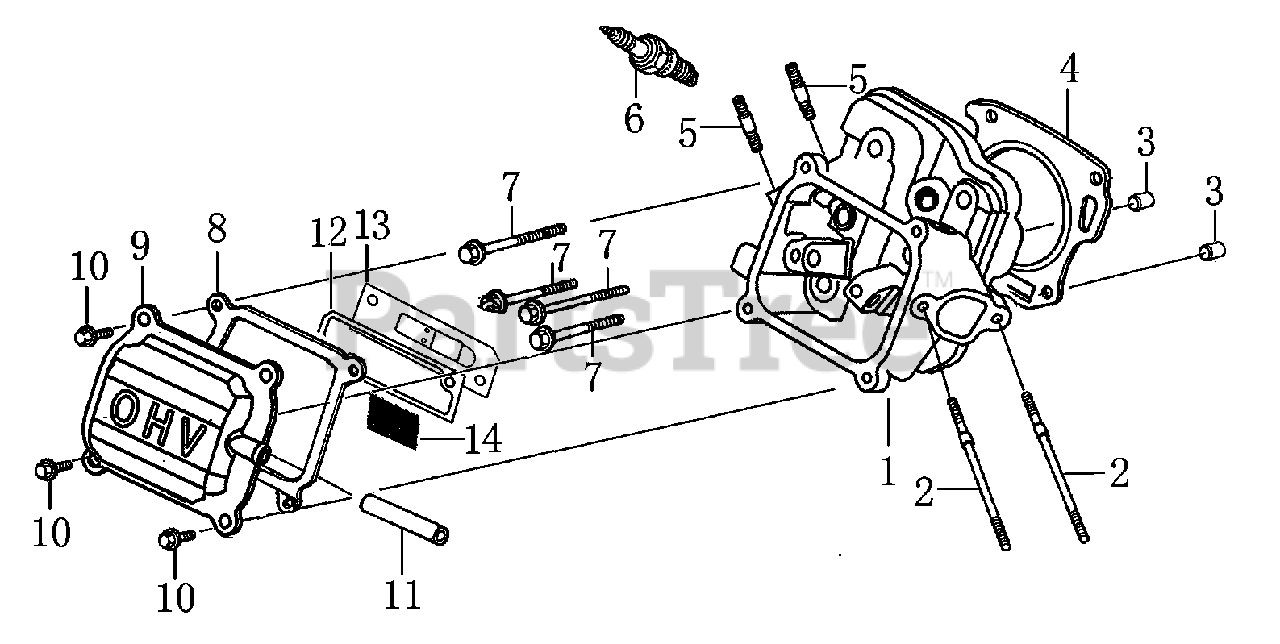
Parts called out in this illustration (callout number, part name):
1	HEAD, CYLINDER
2	BOLT, STUD,IN.
3	PIN, DOWEL
4	GASKET, HEAD CYLINDER
5	BOLT, STUD , EX.
6	PLUG, SPARK
7	BOLT, FLANGE 8*60
8	GASKET, HEAD COVER
9	COVER, HEAD
10	BOLT, FLANGE 6*14
11	TUBE, BREATHER
12	GASKET, BREATHER CHAMBER
13	CAP, BREATHER CHAMBER
14	OIL STRAINER
